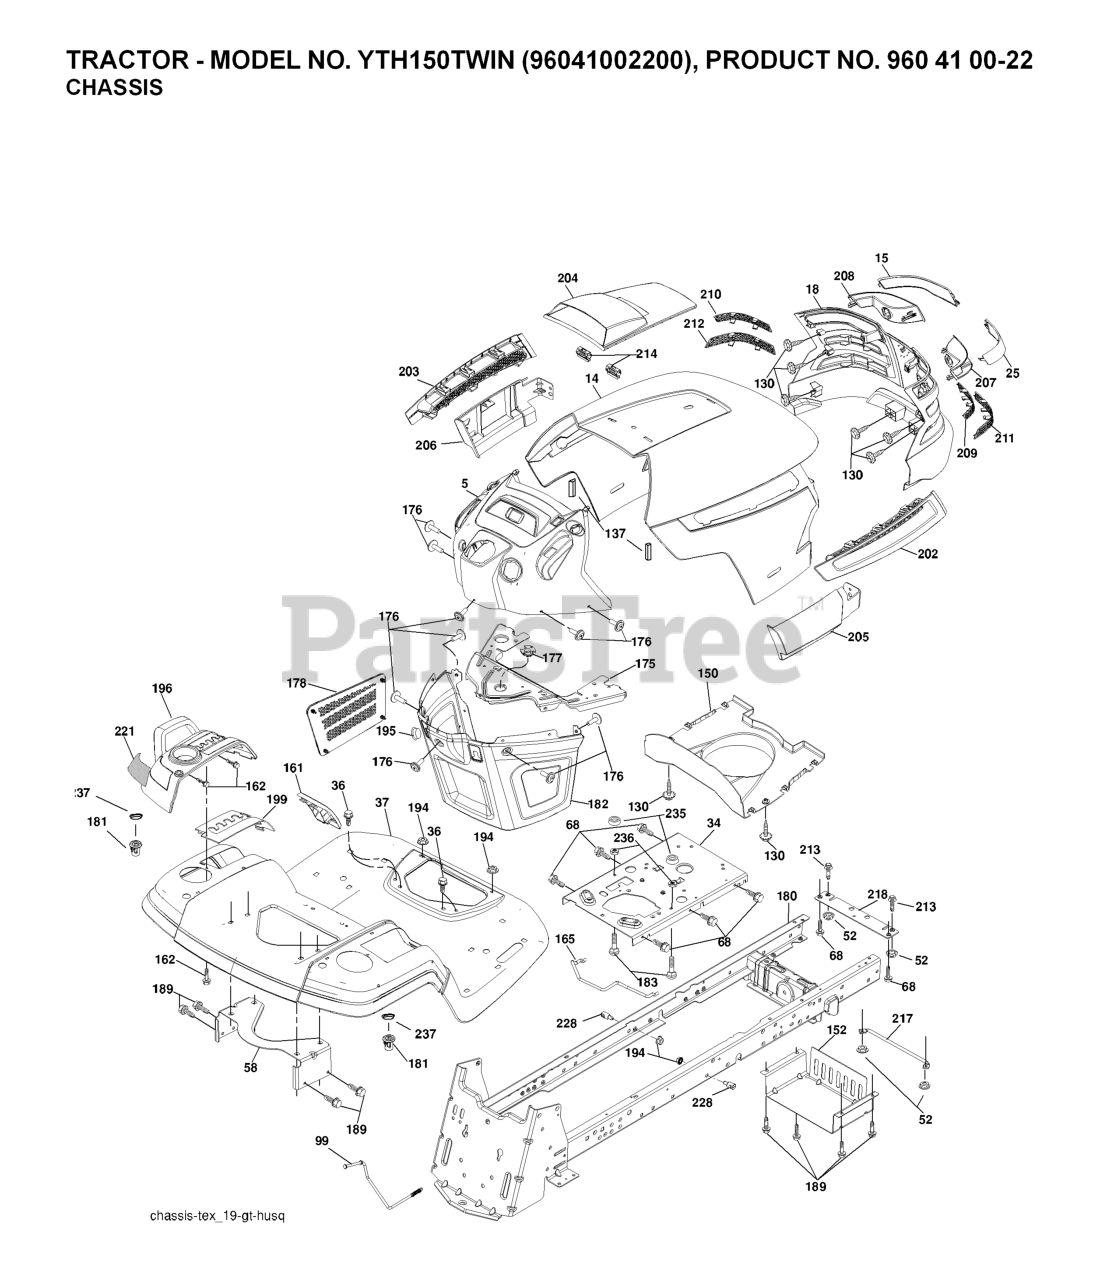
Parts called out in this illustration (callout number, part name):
5	DASH.ASM.HUSQ.GT.E.RECT.W/CK
14	HOOD
15	LENS.LH.TEX.GT.HUSQ.CL
18	GRILLE.ASM.TX.GT.HUSQ
25	LENS.RH.TEX.GT.HUSQ.CL
34	PLATE.ENGINE.WELDED.CHASSIS
36	SCREW 5/16"
37	FENDER.PNT.TX.GT.CH/FW.ORANGE
52	LOCKNUT
58	BRKT.SUPPORT.FNDR/TANK
68	Screw 5/16-18 x 1/2 Hex, Self Tapping 5/16-18 x 1/2
99	ROD.BYPASS.HYDRO.0510/0610.GT
130	SCREW
150	AIR.DUCT.TEXGT.HUSQ.31
152	SHIELD.BROWNING.W/TEX
161	CONSOLE.FUEL.WINDOW.HU
162	SCREW.HI-LO.CONSOLE
165	SUPPORT.TANK.REAR.W/TEX
175	PLATE.CROSSMEMBER.HUSQ
176	SCREW.#10-24X5/8.RN.QU
177	BUSHING, STEERING
178	CARGO.ASM.NET.TXGT.W/C
180	CHASSIS.WLDMT.TX.GT.05
181	BUSHING.MNT.FEND.CRGO.
182	DASH.LOWER.COMMON.12V.
183	BOLT.5/16-18X1-1/4 FULL.THREAD
189	SCREW
194	NUT LOCK HEX FLANGE 5/16-18
195	PLUG.HOLE.DASH.LOWER.12V.BLK
196	RP CONSOLE.ASM.DECKLFT.W/
199	PLATE.DECK.LIFT.HUSQVARNA.GT
202	VENT.SIDE.HOOD.HUSQ.RH.GREY
203	VENT.SIDE.HOOD.HUSQ.LH.GRAY
204	VENT.TOP.HOOD.HUSQVARN
205	SKIRT.HOOD.SIDE.HUSQ.RH.GREY
206	SKIRT.HOOD.SIDE.HUSQ.LH.GREY
207	BEZEL.RH.TEX.GT.HUSQ
208	BEZEL.LH.TEX.GT.HUSQ
209	INSERT.HEX.GRILL.HUSQ.GREY
210	INSERT.HEX.GRILL.HUSQ.
211	INSERT.HEX.GRILL.HUSQ.
212	INSERT.HEX.GRILL.HUSQ.
213	BOLT
214	CLIP.RETAINER.TINNER.
217	ROD PIVOT CHASSIS/HOOD
218	X-PIECE.HOOD.STOP.NON/
221	REFLECTOR.LH.TEX GT HU
228	STUD.FASTNER.W/ANTI-ROTATE
235	SPACER FENDER
236	NUT.CENTERLOCK.5/16-
237	PLUG.MOUNT.CARGO.BLK
